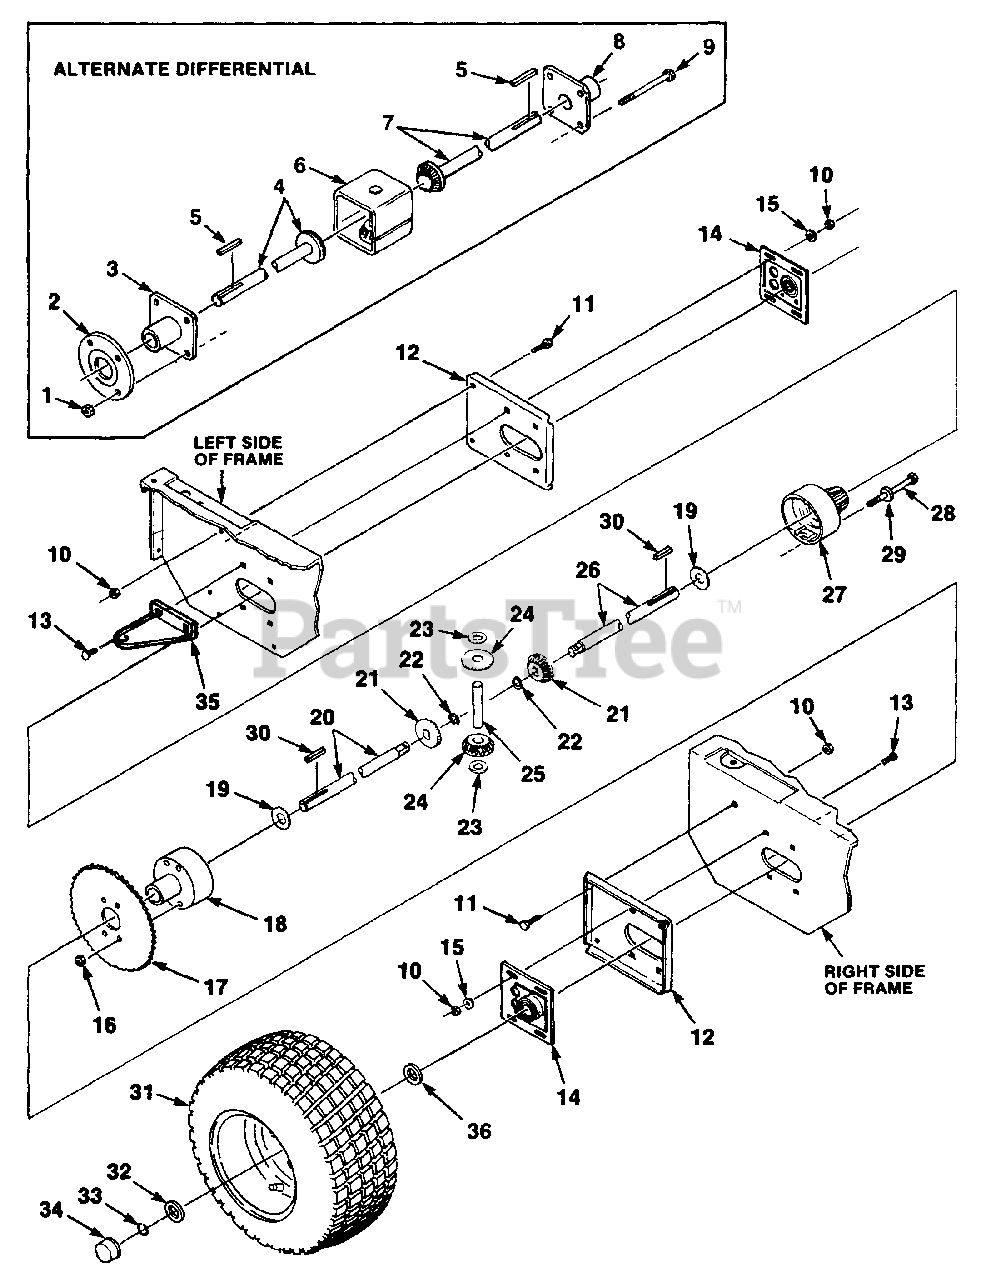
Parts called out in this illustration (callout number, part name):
2	SPACER- Differential
3	CAP & BEARING (R.H.)
4	AXLE- R.H. w/Gear
5	KEY 3/16 x 3/16 x 2 1/2
6	HOUSING & GEAR
7	AXLE- L.H. w/Gear
8	CAP & BEARING (L.H.)
9	SCREW- Hex 5/16-18 x 4
10	NUT- 1/4-20 lock
11	SCREW 1/4-20 x 5/8
12	SUPPORT- Frame
13	BOLT- 1/4-20 x 3/4
14	RETAINER & BEARING
15	WASHER 1/4
16	NUT- Centerlock 3/8-16
17	SPROCKET- 48 tooth
18	HOUSING- L.H. Gear
20	AXLE-Short (RH)
21	GEAR- Bevel
22	RING- Snap
23	WASHER- Thrust
24	GEAR- Pinion
25	PIN- Drive
26	AXLE-Long(LH)
27	GEAR HOUSING- R.H.
28	SCREW- Mach hex hd.
31	TIRE & HUB (rear)
32	SPACER- Axle
33	RING- Retaining
36	WASHER- Flat
